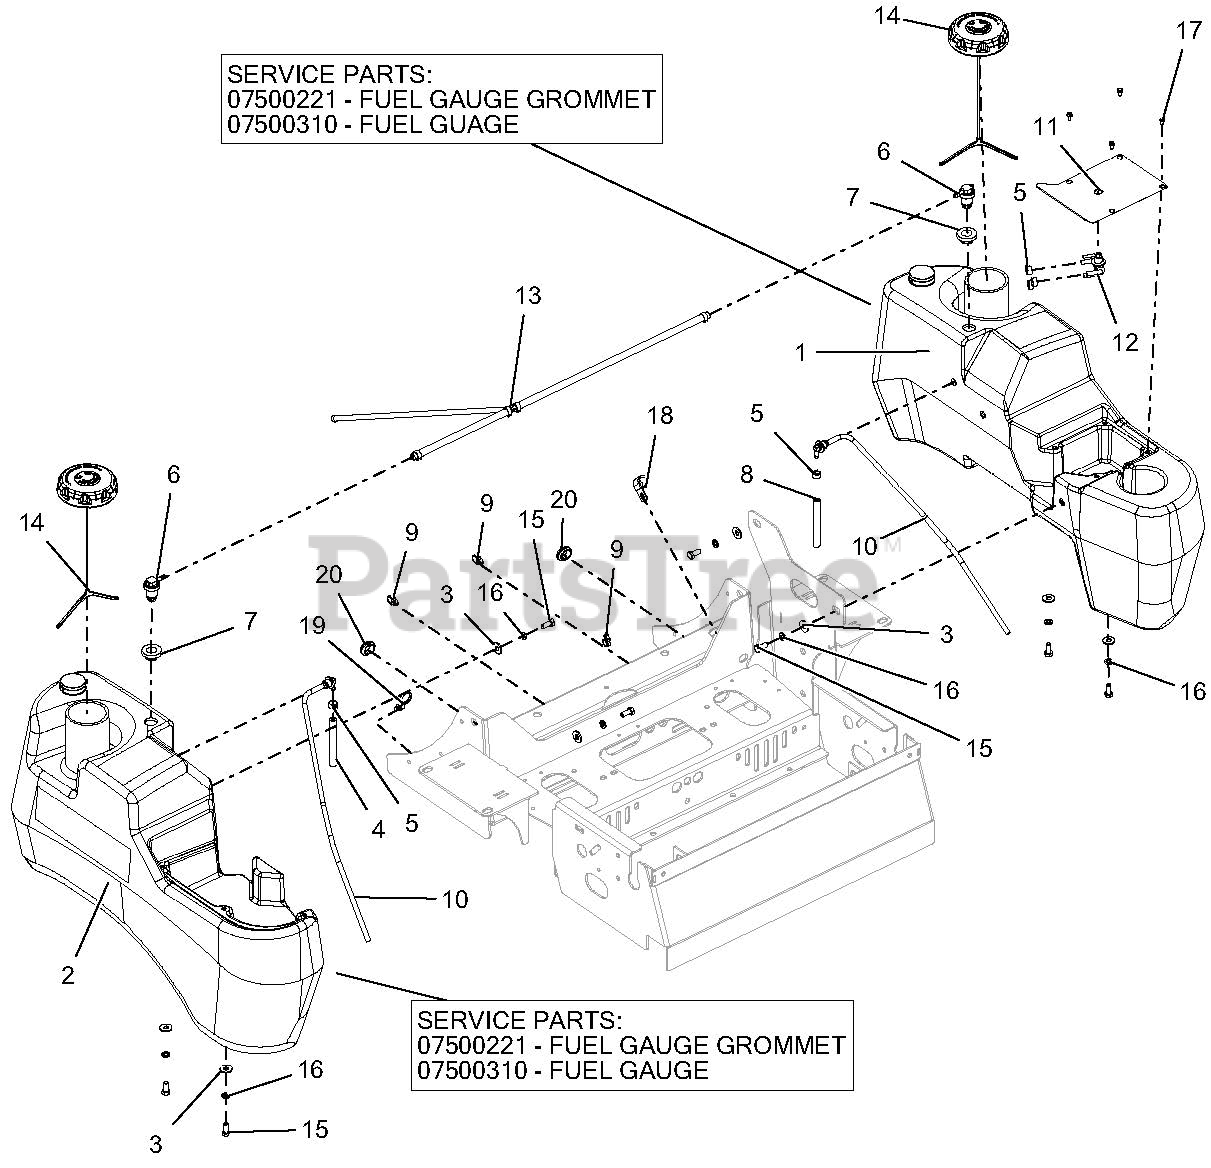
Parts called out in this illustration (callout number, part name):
1	ASSY-LH LARGE FUEL TANK W/MECH GAUGE-GAS
1	FUEL GAUGE GROMMET
1	FUEL GAUGE
2	ASSY-RH LARGE FUEL TANK W/MECH GAUGE-GAS
2	FUEL GAUGE GROMMET
2	FUEL GAUGE
3	WSHR-FL-STL.38X.875X.083 YWZC
4	.25 LOW-PERM GAS HOSE 54.00" LG - RH TANK TO VALVE
5	CLAMP, FUEL LINE
6	VALVE, 2-WAY
7	GROMMET, REMOTE VENT NITRILE
8	.25 LOW-PERM GAS HOSE 19.00" LG - LH TANK TO VALVE
9	CLIP, ROUTING (.50 ID)
10	ASM, LARGE TANK FUEL PICKUP
11	PLATE, FUEL VALVE MOUNTING-RED
12	VALVE, FUEL
13	PT400, FUEL LINE ASSEMBLY
14	CAP, FUEL VENT-IN AUTOLOCK
15	BLT-HEX .31-18X.75 GR5 YWZC
16	WSHR-LK .31X.078 REG YWZC
17	SCR-MCH 10-24X.38 HWHSTAINLESS
18	CLAMP, CUSHIONED STEEL .75
19	CABLE TIE W/ TREE (.25 HOLE)
20	GROMMET, RUBBER
